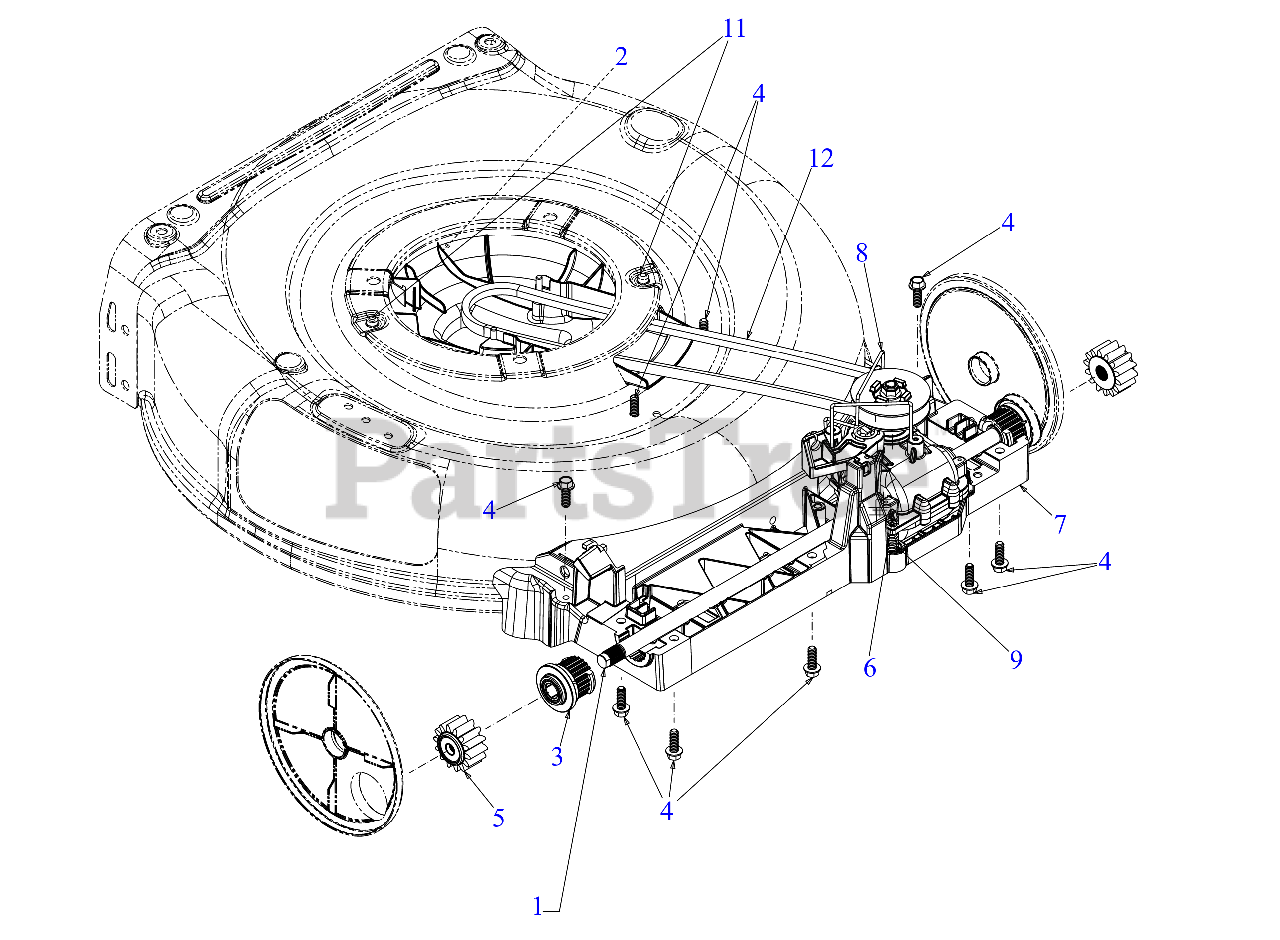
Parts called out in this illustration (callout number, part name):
1	TRANSMISSION ASSEMBLY
2	ENGINE BAFFLE ASSEMBLY
3	BEARING ASSEMBLY
4	SCREW 1/4-15 x .750
5	SPUR GEAR (14T) (RH)
6	SPRING COMPRESSION
7	LOWER TRAY
8	TRANSMISSION WIRE
9	COMPRESSION SPRING
11	SHOULDER SCREW 1/4-20 x .50
12	V-BELT 3L 34.18
